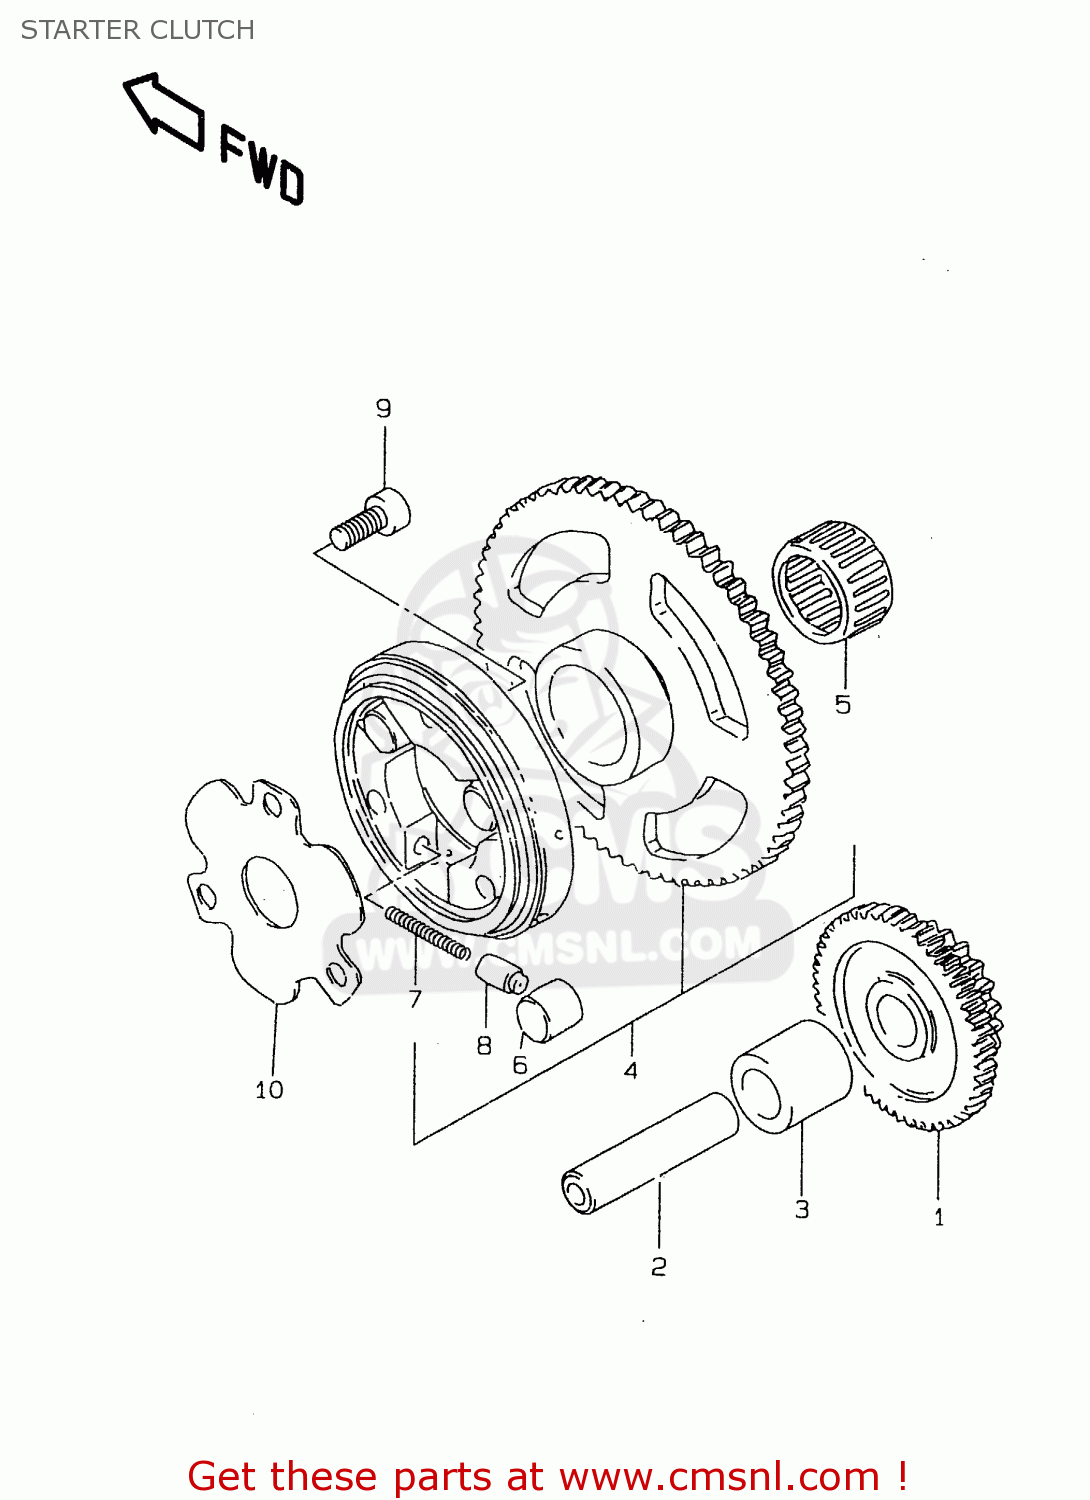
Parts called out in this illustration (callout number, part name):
1	GEAR,STARTER IDLER
2	PIN(7.4X13X56)
3	SPACER(13X19X19)
4	CLUTCH SET,STARTER
5	BEARING(22X28X16)
6	ROLLER(10X11)
7	SPRING
8	PIECE,STARTER CLUTCH PUSH
9	BOLT,OIL FILLE
10	SHIM,STARTER CLUTCH HUB
